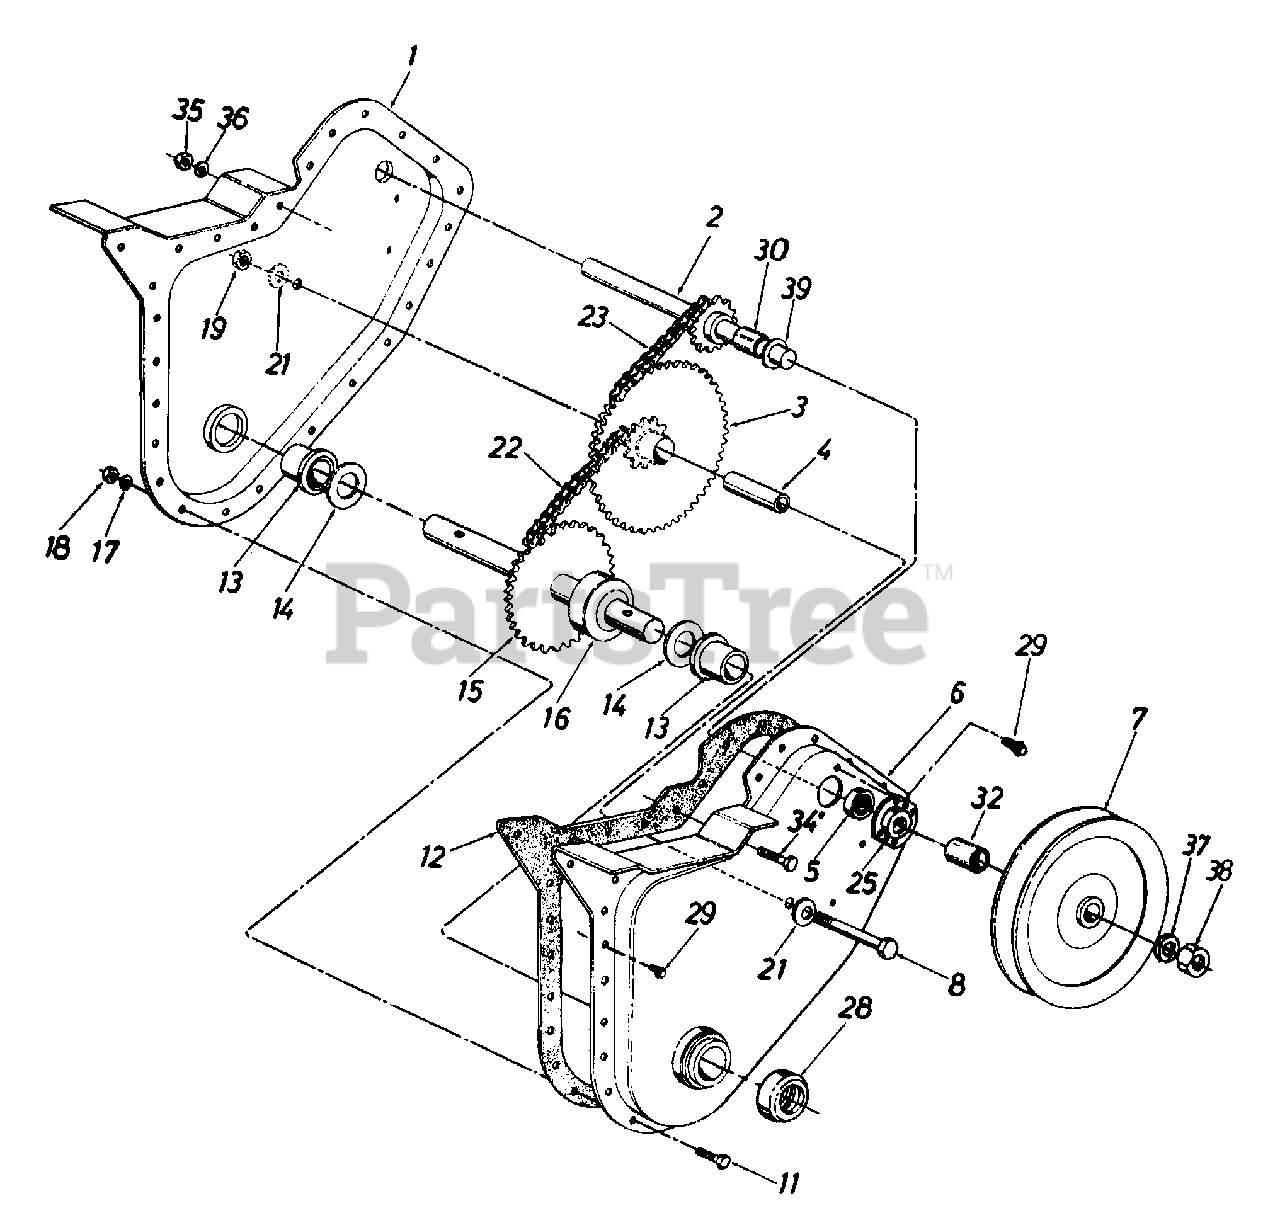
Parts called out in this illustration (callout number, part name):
3	Hub and Sprocket Ass'y.
4	Bearing Inner Race
5	Ball Bearing
8	Hex Bolt 3/8-24 x 2.5"
11	Hex Bolt 1/4-28 x .625"
12	Gasket
13	Flange Brg. .879" I.D.
14	Fl-Wash. .88" I.D. x 1.5"
15	Tine Shaft Ass'y.
16	Spacer 7/8" I.D.
17	L-Wash. 1/4" I.D.
18	Hex Nut 1/4-28 Thd.
19	Hex Ins. L-Nut 3/8-24 Thd.
21	Bell-Wash. .406" I.D.
22	Chain #420 1/2" Pitch 38 Links
23	Chain #35 .375" Pitch 50 Links
25	Bearing Housing
28	Shaft Seal
29	Hex Wash. Hd. Self-Tap Scr. 1/4-
30	Spacer .63" I.D. x .77" O.D. x .38"
32	Spacer .647 x .77"
34	Hex Bolt 5/16-18 x .75" Lg.
35	Hex Nut 5/16-18 Thd.
36	L-Wash. 5/16" I.D.
37	Bell-Wash. .38" I.D. x .88" O.D.
38	Hex Flange L-Nut 3/8-24 Thd.
39	Washer .652 I.D.
